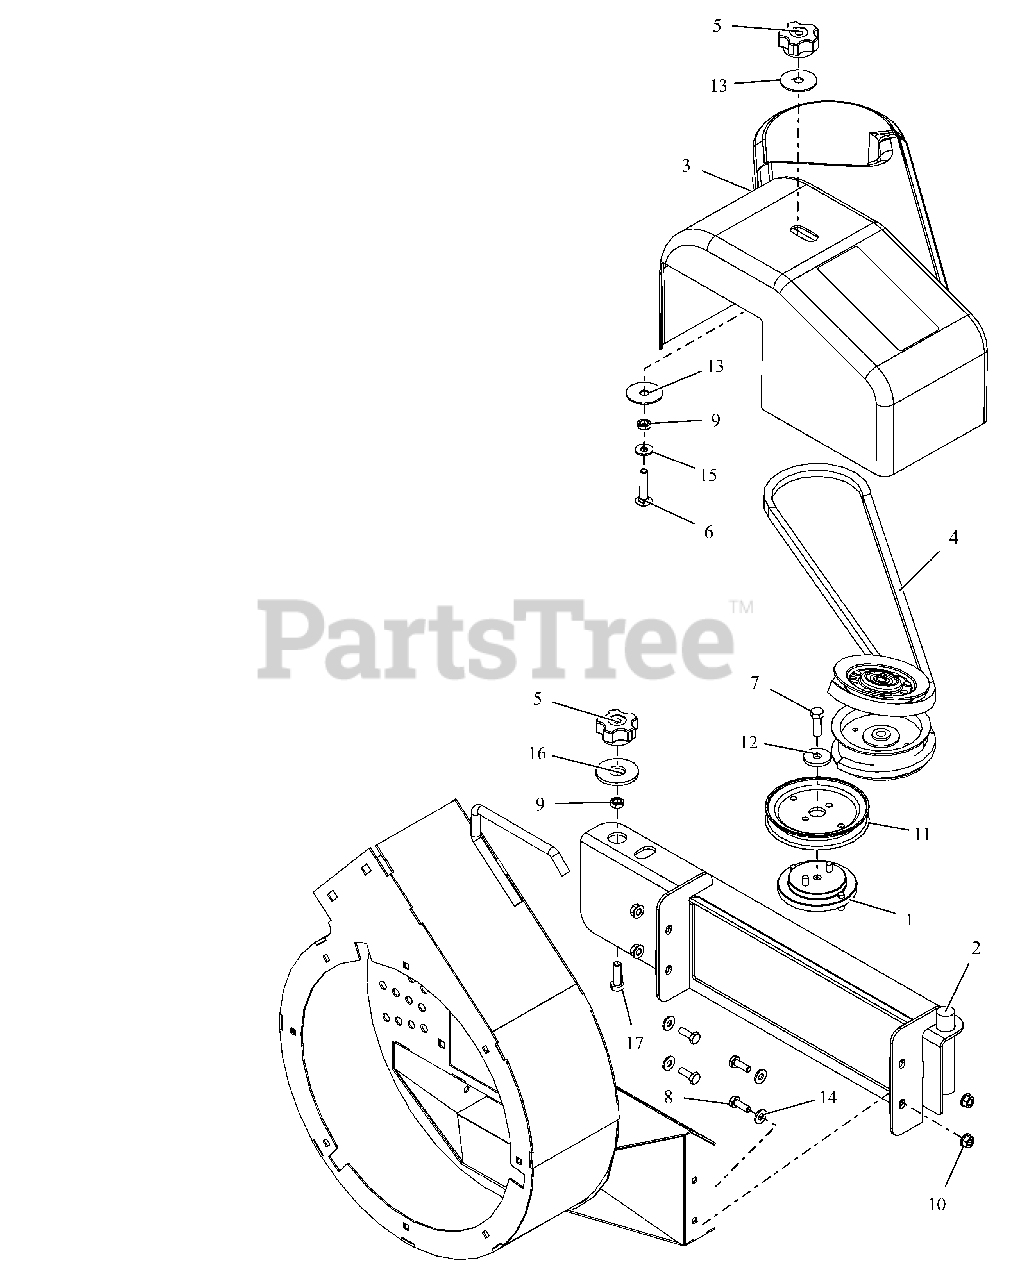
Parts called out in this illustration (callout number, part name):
1	ASM, BAGGER SHEAVE ADAPTER
2	WLDMT, GRASS PUMP MOUNT
3	COVER, BAGGER BELT -W/DECAL
4	V-BELT, HA-WRAPPED
5	KNOB-CLAMPING, .312-18 NYLOC
6	@BLT-RDHDSQNK .31-18X1.50 G5YZ
7	BLT-HEX .31-18X1.00 GR8 M-EPYZ
8	@BLT-HEX .25-20X.75 GR5 YWZC
9	NUT- JAM .312-18 YWZC
10	@NUT-LK-TOP-FLG .25-20 YWZC
11	SHEAVE, SPINDLE (4.25 HA )
12	WSHR-FL-STL .344X1.125X.135
13	WSHR-FL-STL .380X1.50X.062 YWZ
14	@WSHR-FL-STL.281X.62X.065 YWZC
15	@WSHR-FL-STL.312X.734X.065 YWZ
16	@WSHR-FL-STL.688X1.75X.134 YWZ
17	BLT-HEX .31-18X1.00 GR8 YWZC
